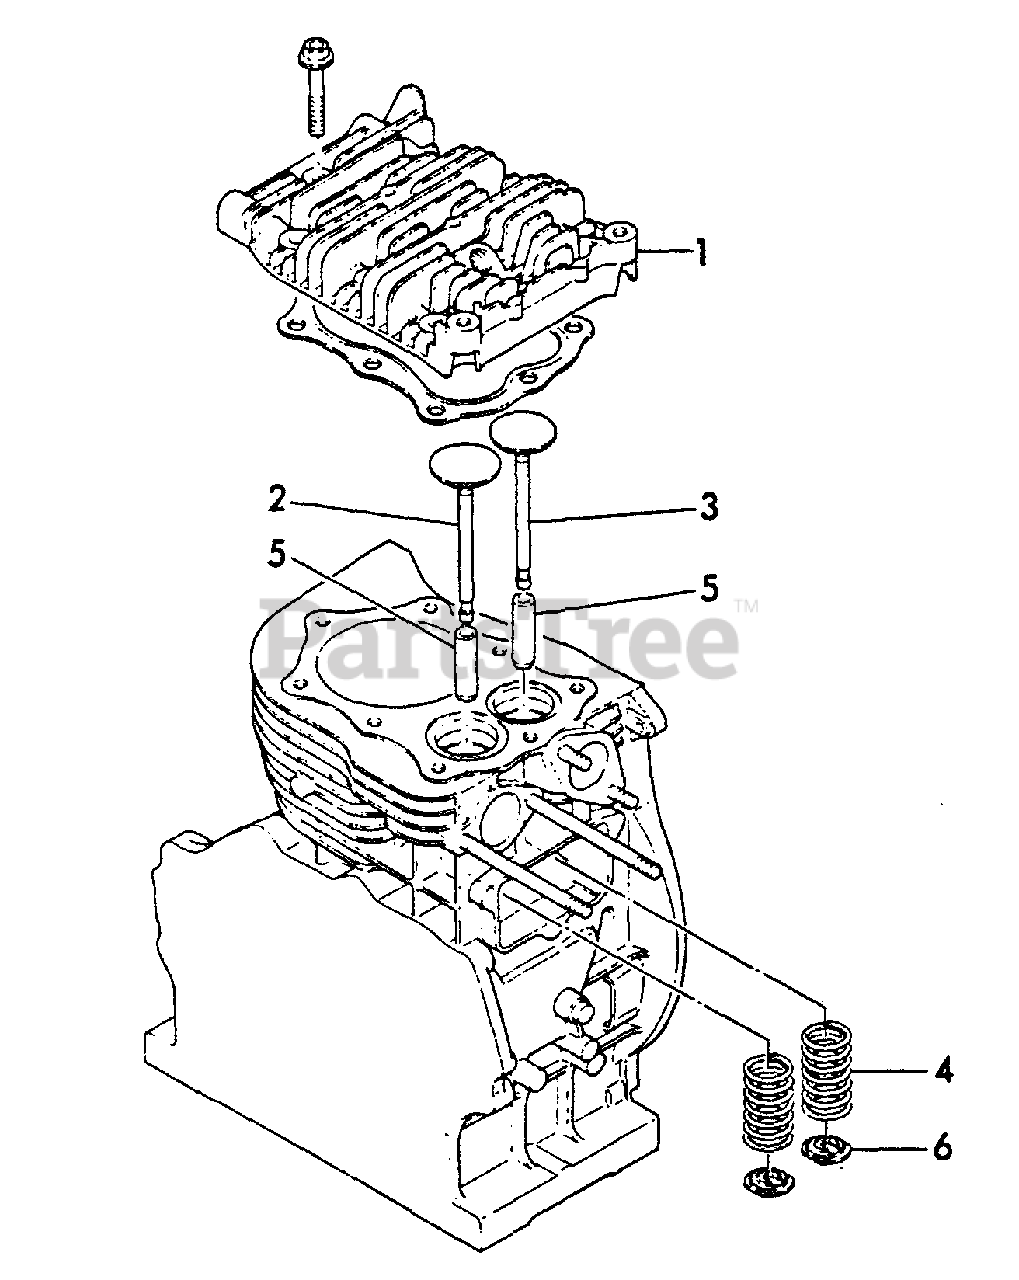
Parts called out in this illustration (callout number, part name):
1	HEAD, CYLINDER
2	VALVE, INTAKE
3	VALVE, EXHAUST
4	SPRING, VALVE
5	GUIDE, VALVE
